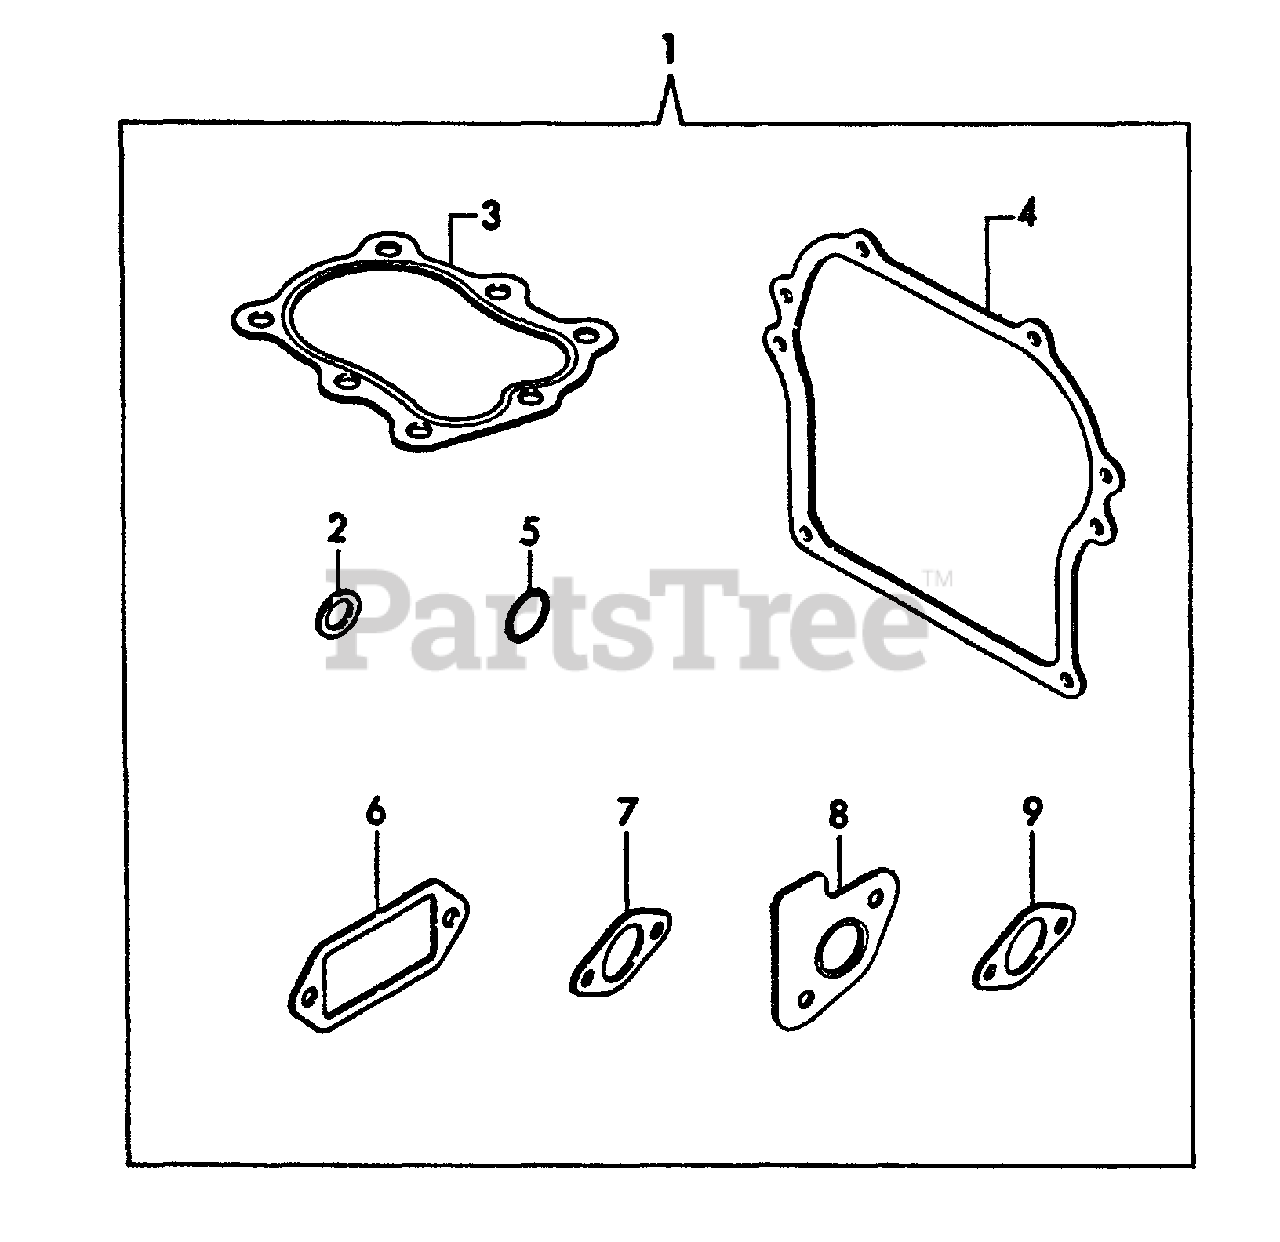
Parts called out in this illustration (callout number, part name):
1	GASKET KIT
2	GASKET
3	GASKET, CYLINDER
4	GASKET
5	O-RING - 18
6	GASKET
7	GASKET, INTAKE
8	GASKET, EXHAUST
9	GASKET, EXHAUST
